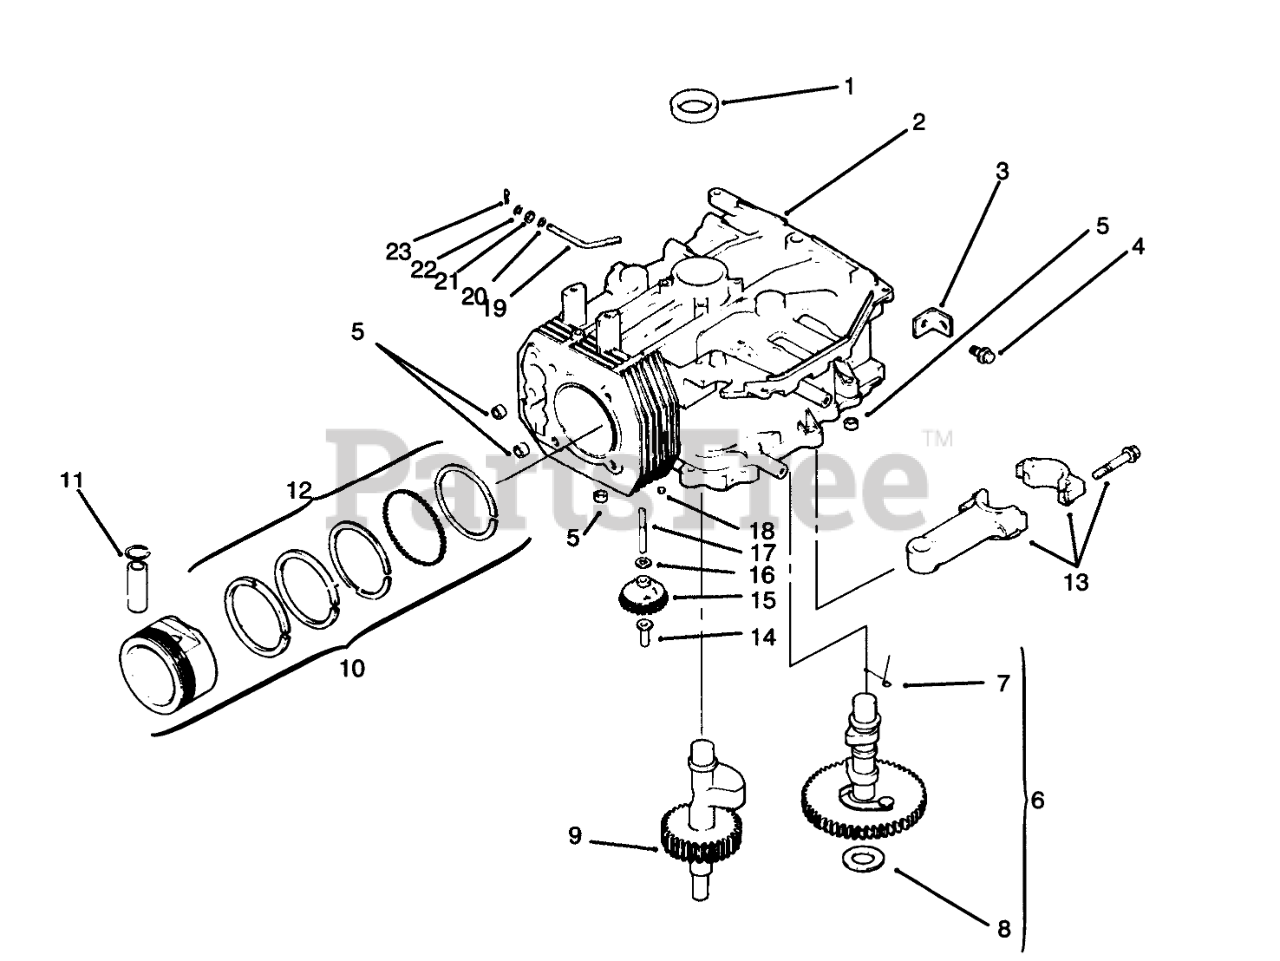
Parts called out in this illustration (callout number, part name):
1	Seal-Oil
3	Strap-Liting
4	Screw
5	Pin-Dowel
6	Camshaft Assembly
7	Spring-Actuating
8	Shim-Camshaft
9	Shaft-Balance
10	Piston ASM STD Incl 11-2
10	Piston ASM .25 Incl 11-2
10	Piston ASM .50 Incl 11-2
11	Retainer-Piston Pin
12	Ring Set STD
12	Ring Set .25
12	Ring Set .50
13	Connecting Rod STD
13	Connecting Rod .25
14	Pin-Governor
15	Gear-Governor ASM
16	Washer
17	Shaft-Govenor Gear
19	Rod-Push
21	Seal
22	Washer
23	Pin-Hitch
